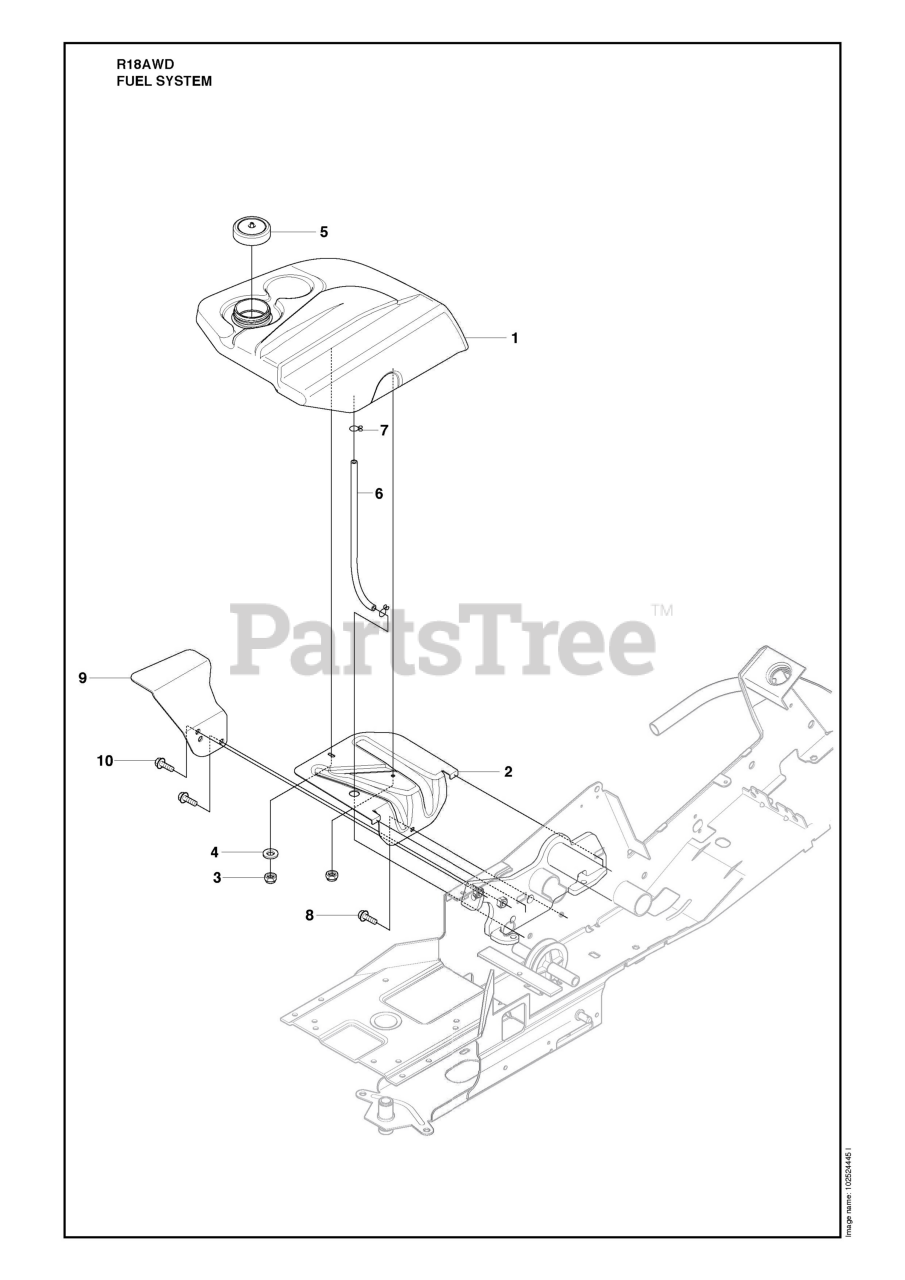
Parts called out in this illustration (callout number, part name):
3	LOCKNUT M6
4	WASHER
10	Screw, M10 X 25
